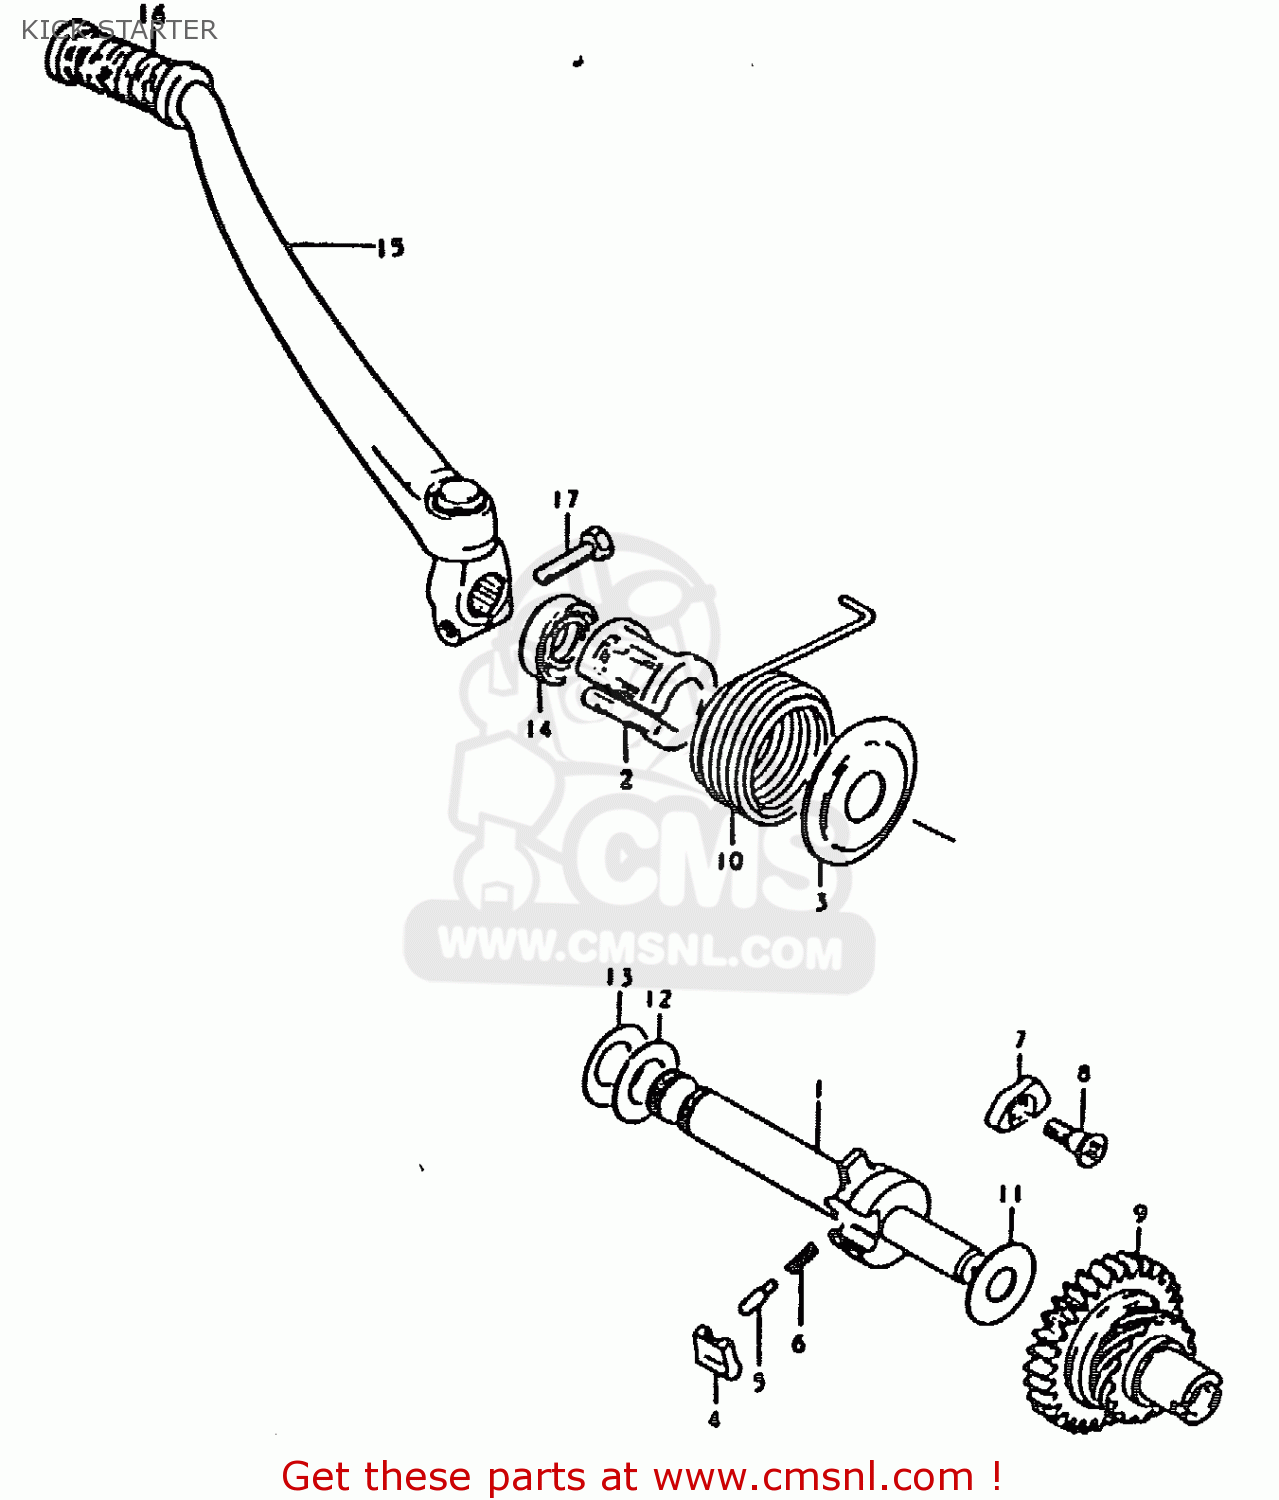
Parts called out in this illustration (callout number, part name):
1	SHAFT,KICK STARTER
2	GUIDE,KICK STARTER SFT SPRING
3	HOLDER,KICK STARTER SHAFT SPR
4	PAWL,KICK STARTER
5	PIN(5X15.5)
6	SPRING
7	LIFTER,KICK STARTER PAWL
8	SCREW(6X19)
9	GEAR,KICK STARTER DRIIVE
10	SPRING
11	WASHER(12X30X3)
12	WASHER(16X30X0.5)
13	WASHER
14	SEAL,OIL(16X30X8)
15	LEVER ASSEMBLY,KICK STARTER
16	RUBBER,KICK STARTER PEDAL
17	BOLT
